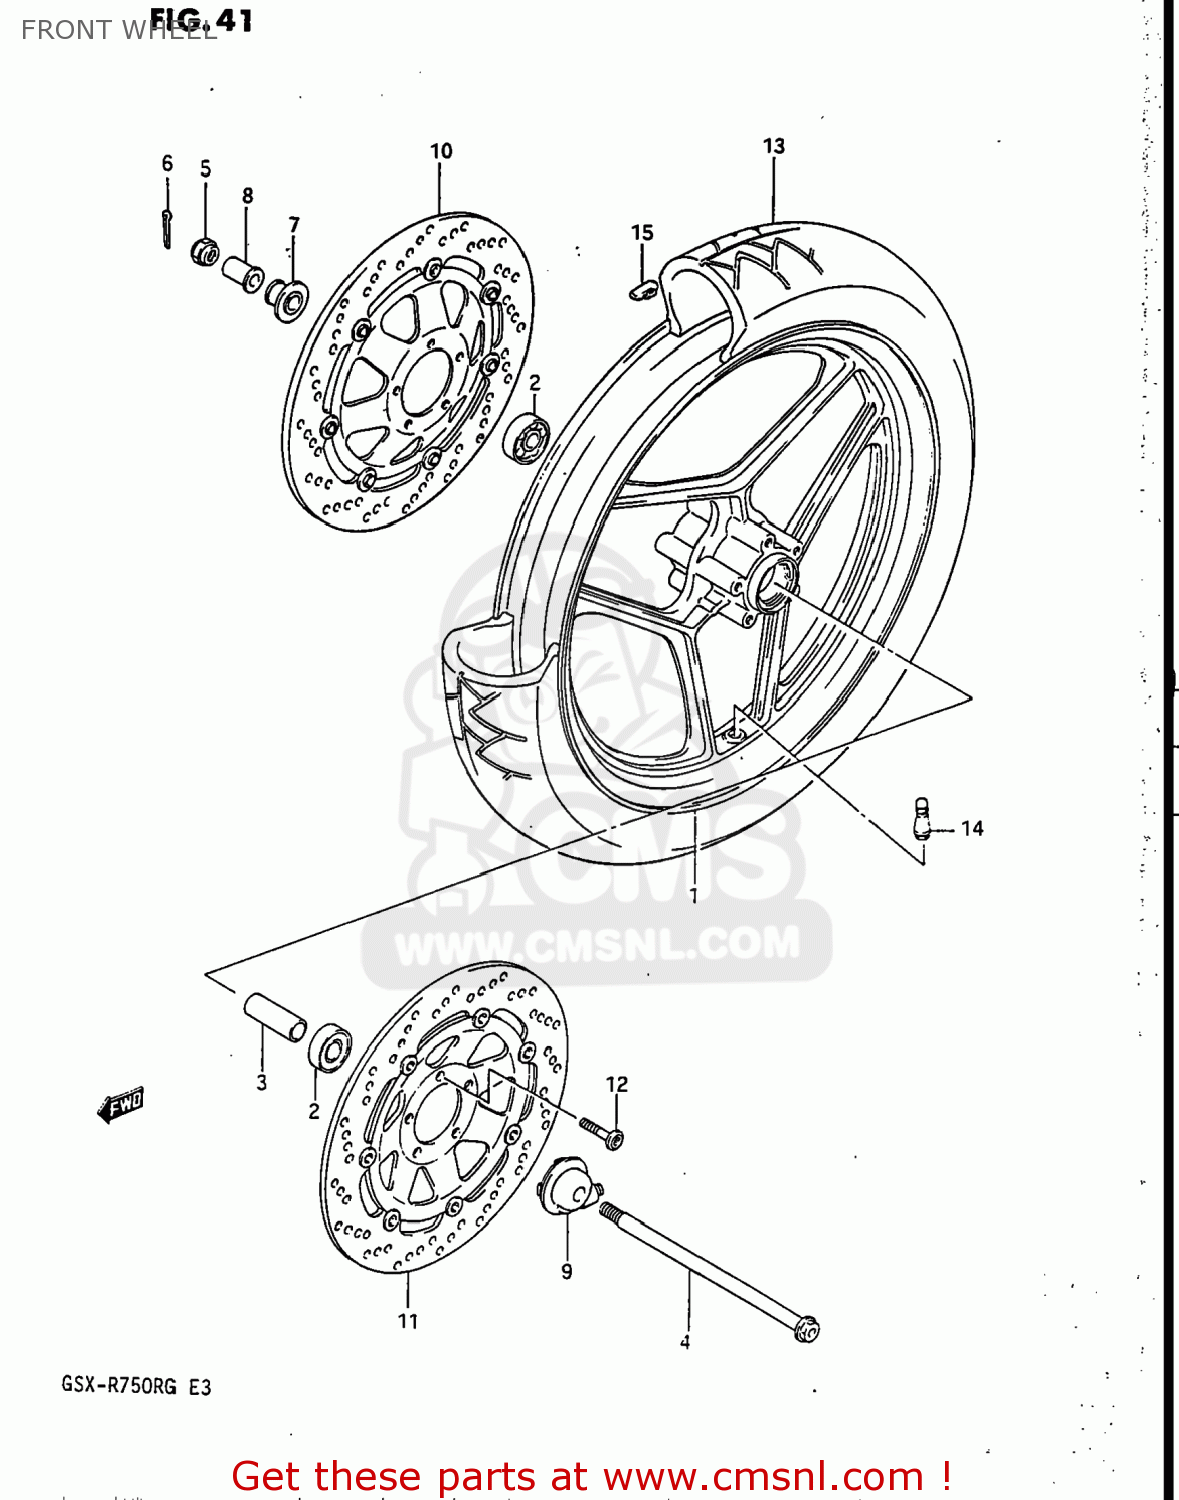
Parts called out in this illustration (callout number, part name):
1	WHEEL,FRONT
2	BEARING
3	SPACER(15.3X21.7X77)
4	AXLE,FR
5	NUT (12MM)
6	COTTER PIN
7	SPACER,FR HUB BEARING,R
8	SPACER
9	BOX ASSEMBLY,SPEEDOMETER GEAR
10	DISC,BRAKE
11	DISC,BRAKE
12	BOLT
13	TIRE,FRONT
14	VALVE,TIRE
15	BALANCER,WHEEL
